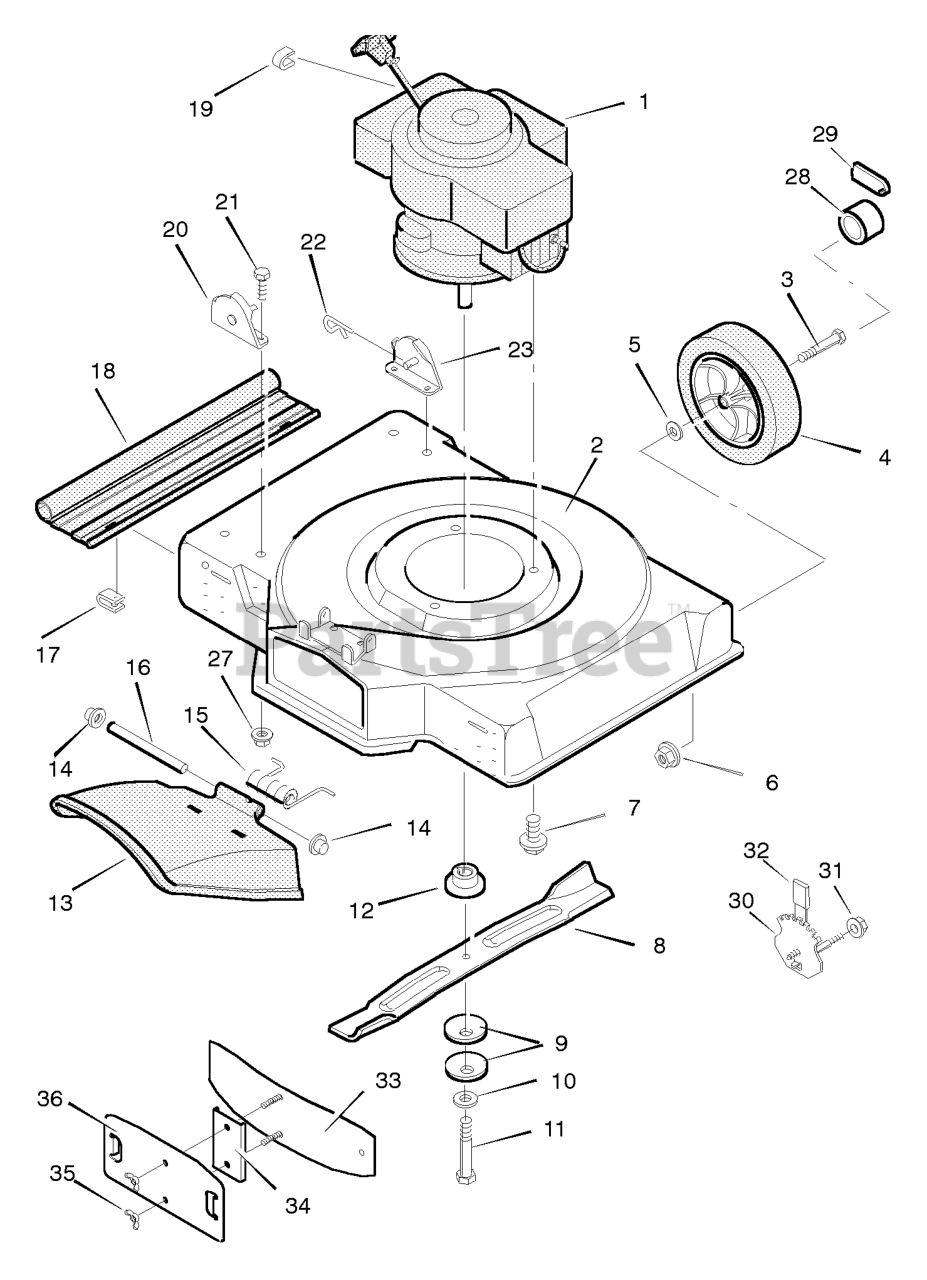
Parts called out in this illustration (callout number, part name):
1	Engine *
2	Housing
3	Bolt, Axle
4	Wheel and Tire *
6	Locknut, Flange
7	Bolt, Engine
9	Washer, Belleville
11	Bolt, Hex
12	Adapter, Blade
13	Deflector, Chute
14	Push- On Cap
16	Pin, Pivot
17	Retainer
18	Deflector, Rear
19	Stop, Rope
20	Bracket, Right Handle
22	Pin, Hair
23	Bracket, Left Handle
27	Nut
28	Hub Cap
29	Hub Cap
30	Adjuster, Height
31	Locknut, Flange
35	Wingnut
